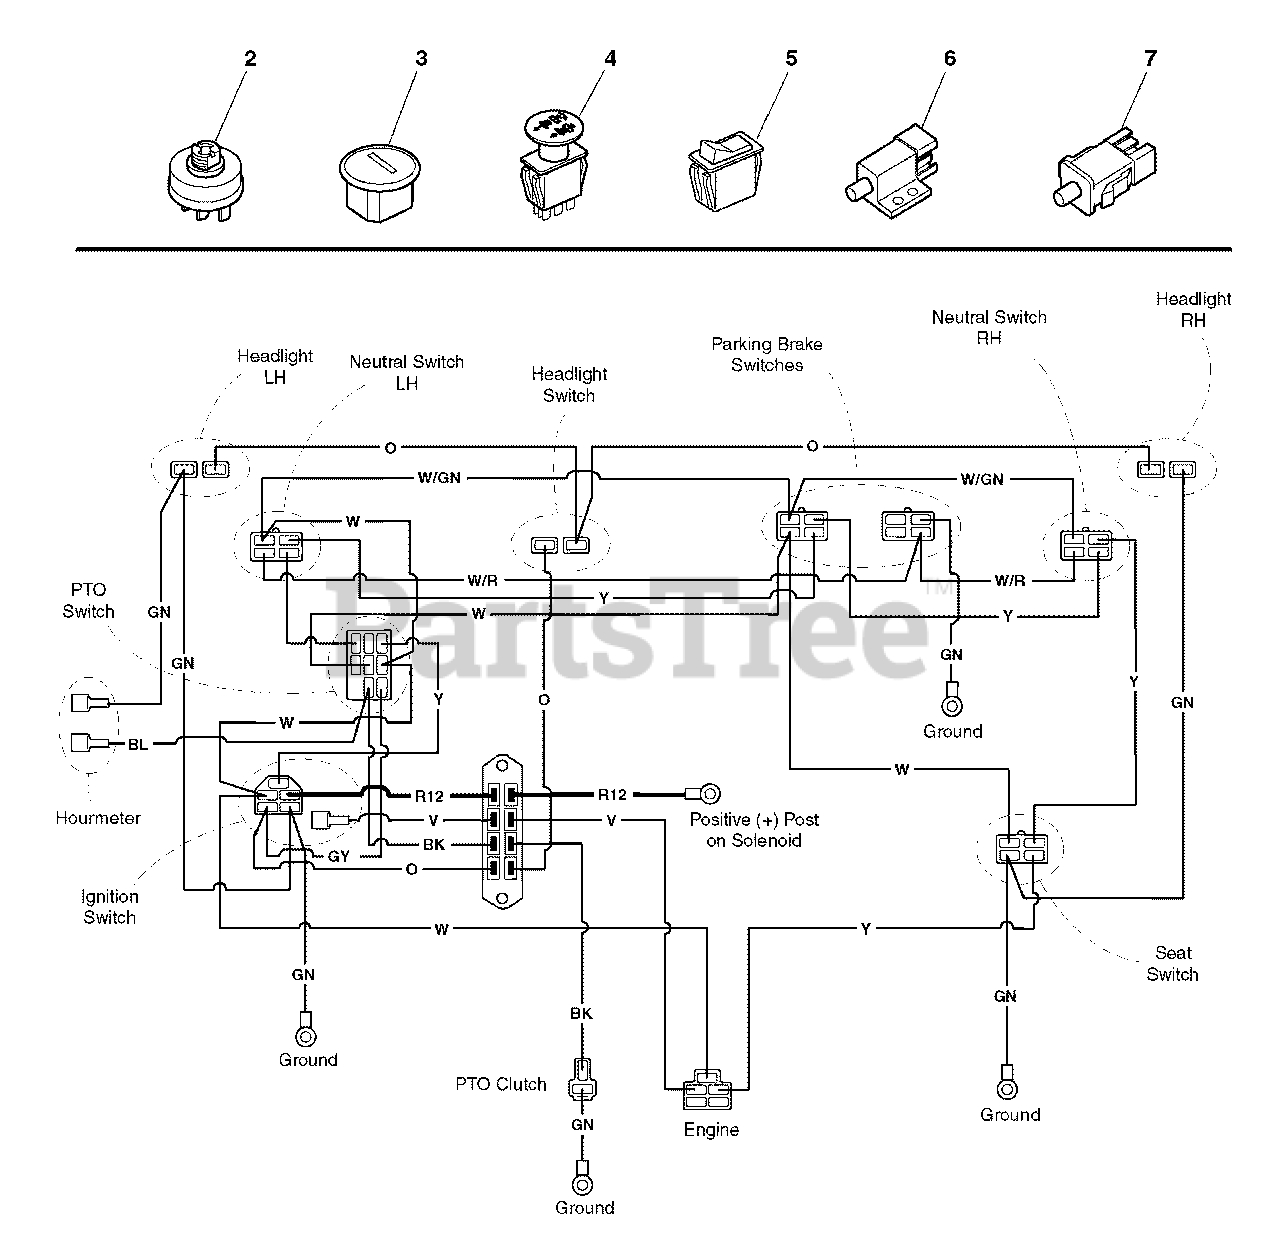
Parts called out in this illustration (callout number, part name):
1	ZT2354 Wire Harness
2	SWITCH, Ignition
4	SWITCH, PTO
5	SWITCH, Headlight
6	SWITCH, PLUNGER, N.O./N.C.
7	SWITCH, DP NO/NC SNAP-IN
